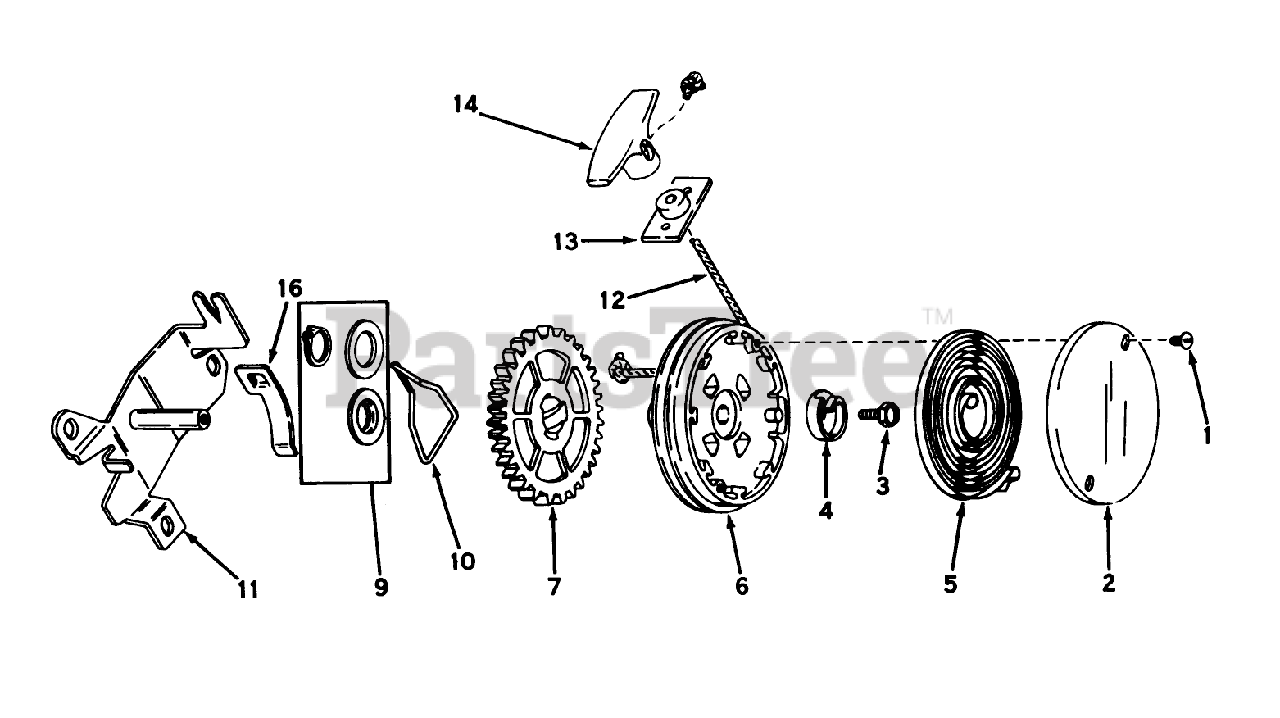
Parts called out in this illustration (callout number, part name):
1	Screw, Cover
2	Cover, Spring
3	Screw, Hex Washer Head
4	Hub Spring
5	Spring, Rewind
6	Pulley Assy. (Incl. No. 9)
9	Kit, Thrust Wash. Snap Rg.
10	Brake
11	Bracket Assy. Mounting
12	Rope, Starter
13	Bracket Assy.
14	Handle-Starter
16	Clip Rope
